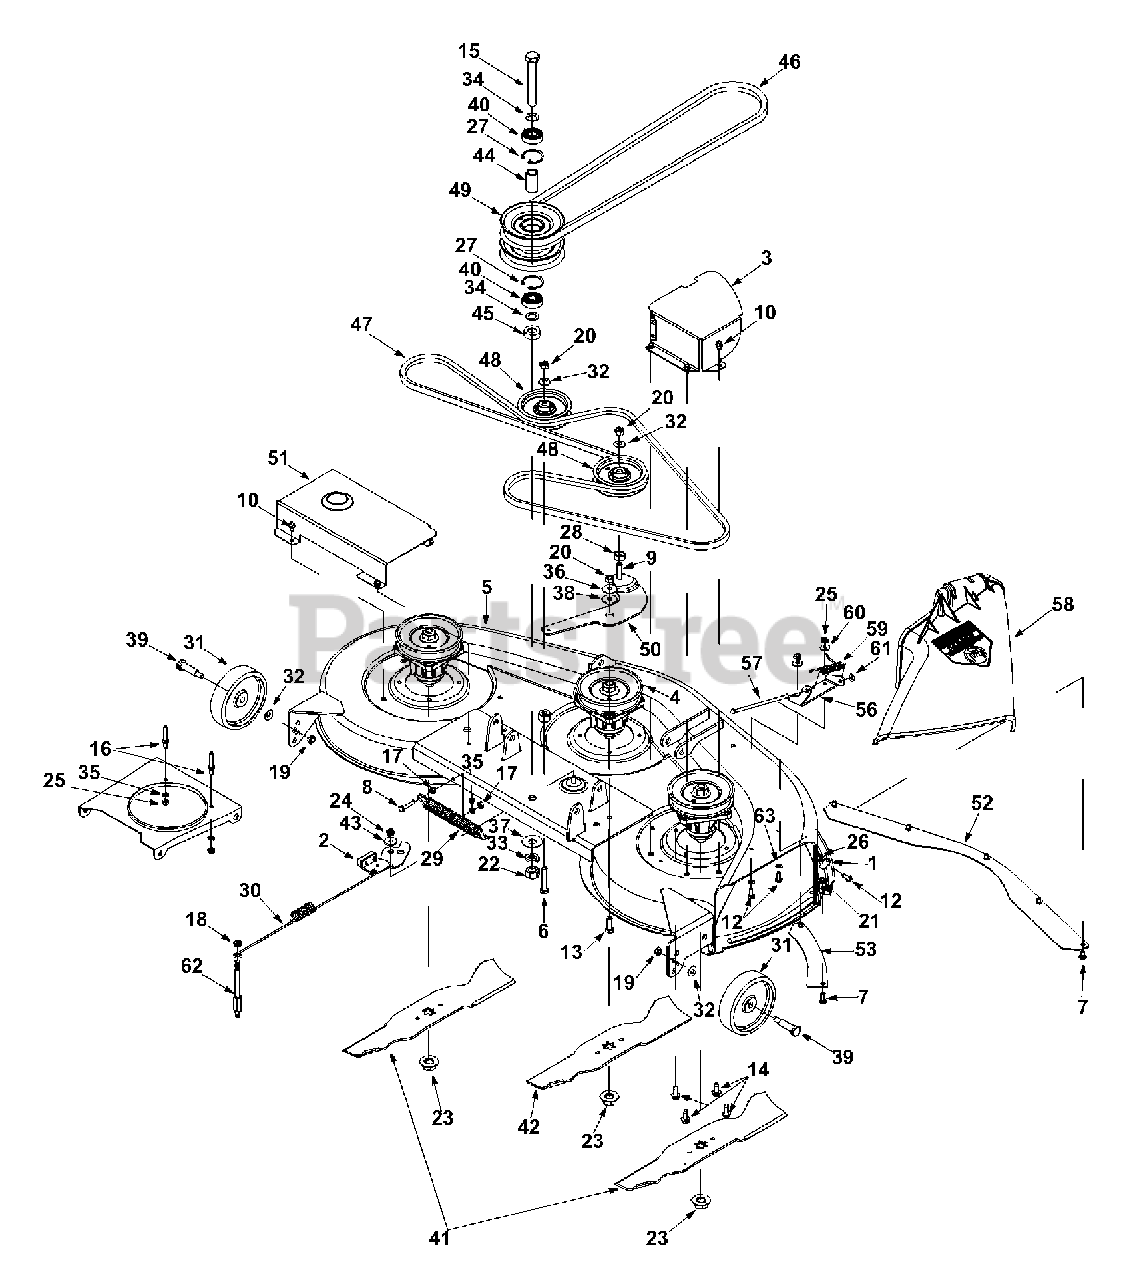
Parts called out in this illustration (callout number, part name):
1	Retainer Hook Brkt.
2	Deck Deck Brake Brkt Ass'y
4	Spindle Ass'y
7	Carriage Bolt 1/4-20 x .5" Lg.
8	Hex Bolt 1/4-28 x 1.25" Lg.
9	Hex Bolt 3/8-24 x 2" Lg.
10	Hex Wash. Hd. TT-Tap Scr.
12	Hex Bolt 1/4-20 x .62" Lg.
13	Hex Bolt 3/8-24 x 1" Lg.
14	Hex Flange Bolt 5/16-24 x .75"
15	Hex Bolt 5/8-18 x 4.25" Lg.
16	Belt Guard Pin
17	Hex Nut 1/4-28 Thd.
18	Hex Center L-Nut 5/16-18
19	Hex Top Jam Nut 3/8-16 Thd.
20	Hex Nut 3/8-24 Gr. 5
21	Hex Sems Nut 1/4-20
22	Hex Nut 5/8-18 Gr.5
23	Hex Flange L-Nut 5/8-18 Thd.
24	Hex Ins. L-Nut 5/16-18 Thd.
25	Hex Nut 1/4-20 Gr.5
26	Hex Lock Nut 1/4-20
27	Internal Snap Ring
28	Slide Cap
29	Ext. Spring .88" O.D. x 6.17"
30	Ext. Spring .788" O.D. x 15.5"
31	Deck Wheel-5"
32	Bell-Wash 3/8" x .87" x .064"
33	L-Wash. 5/8" I.D.
34	Fl-Wash. .635" I.D. x 1" O.D.
35	L-Wash. 1/4" I.D.
36	Bell-Wash. 3/8" x 1.125" x .062"
37	Fl-Wash. .635" I.D.
38	Shoulder Spacer .625" I.D.
39	Shld. Bolt .498" x 1.525"
40	Ball Brg. .625" I.D. x 1.574" O.D.
41	Blade 16.28" Lg. (L.H. & R.H.)
42	Blade 14.88" Lg. (Middle)
43	Shoulder Spacer
44	Spacer .635" I.D. x .088" O.D.
45	Spacer .635" I.D. x 1" O.D.
46	V Belt
47	V Belt
48	Idler Pulley
49	Pulley Double Deck
56	Hinge Brkt.
57	Hinge Pin
58	Chute Ass'y Comp.
59	Torsion Spring
60	Bell. Wash. .265 x.75
61	Speed Nut Cap
62	Return Spring Stud
63	Push Nut
17258C-0637	Deck Belt Cover, 46" Black - POWDER BLACK (0637)
17258C-0638	Deck Belt Cover, 46" Black - MTD/TROY-BILT RED (0638)
17258C-0648	Deck Belt Cover, 46" Black - TECH GRAY (0648)
17258C-0665	COVER:BELT:DECK 46 - YARDMAN GREEN (0665)
17258C-0691	COVER:BELT:DECK 46 - BLACK JACK (0691)
